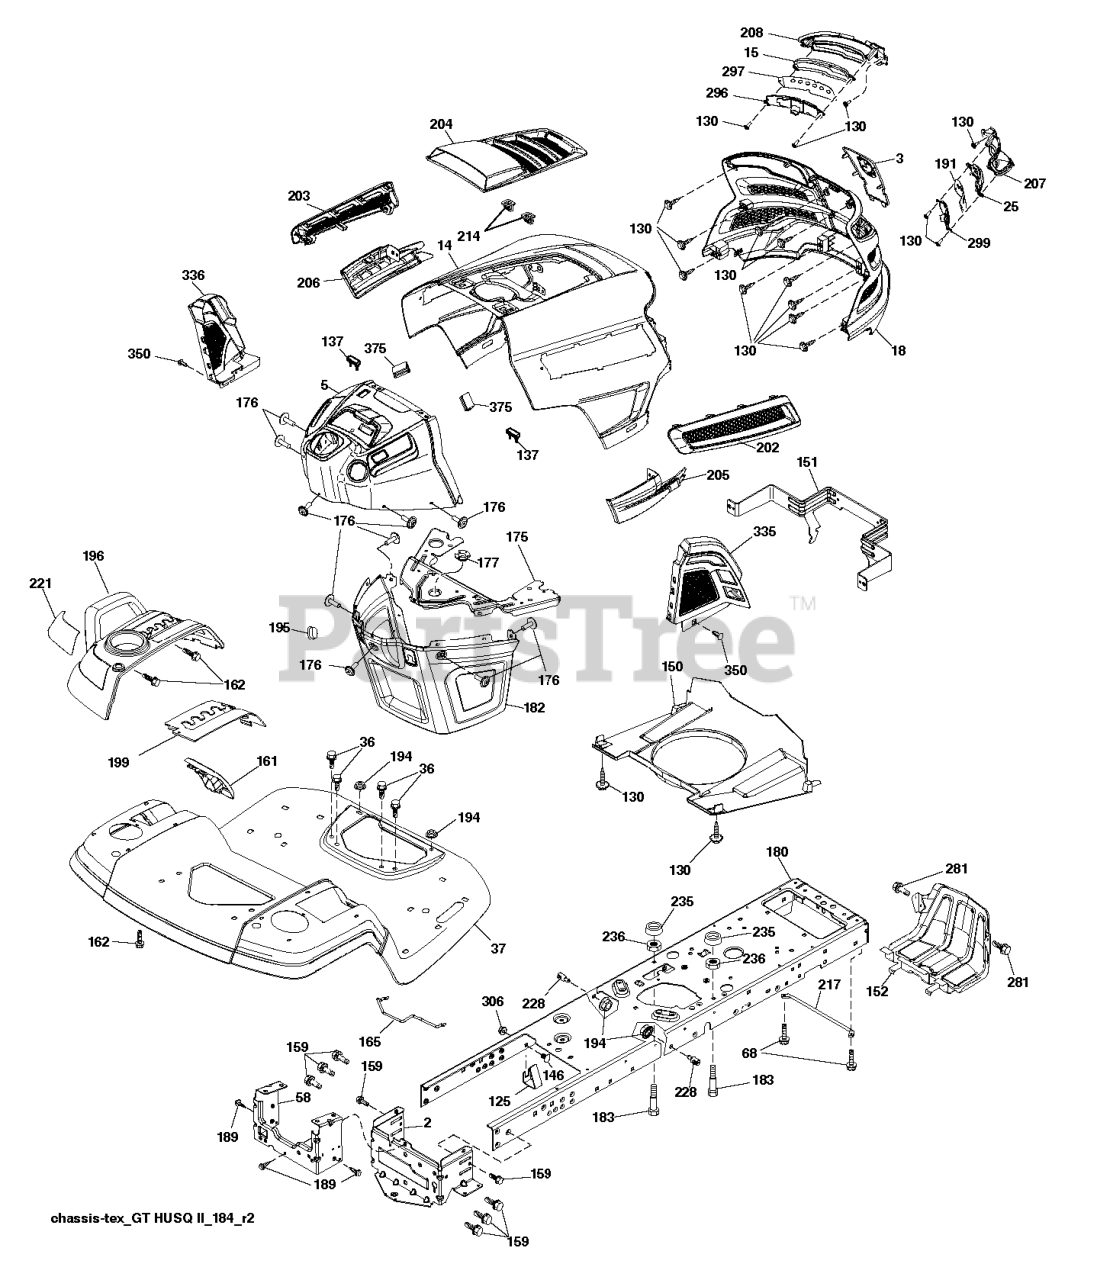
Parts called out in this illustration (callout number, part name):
2	DRAWBAR.LOWER.2PC.18/22
3	APPLIQUE.SUBASM.GT.HUSQ.II
5	DASH.UPR.GT2.DUAL.RD.PT
14	HOOD.ASM.HUSQVARNA.GT.TEX.ORAN
15	LED LIGHT.LH
25	LENS.RH
36	SCREW 5/16"
37	FENDER.PNT.TX.GT.CH/FW/DL.HUSQ
58	DRAWBAR.UPPER.2PC,LRG.FENDER
68	SCR 5/16-18 X 1/2 SELFTAP ZN
125	CLIP.FUEL.LINE
130	SCREW.#10 X 0.750.BOS
137	BUMPER DASH
146	BOLT.RDHD.SHT.SQNK.3/8-16X5/8
150	AIR DUCT.GTV2(1.66"RING HEIGHT
151	BRACKET.PIVOT.HOOD.GT.HUSQ.II
152	SHIELD.BROWNING.PNT.GT.V2
159	SCREW, 3/8-16X3/4
161	CONSOLE.WINDOW.FUEL.HUSQ.GT
162	SCREW.HI-LO.CONSOLE
165	SUPPORT.TANK.REAR.B/TE
175	PLATE.PNT.CROSSMEMBER.HUSQ/PRE
176	SCREW.#10-24X5/8.RN.QU
177	BUSHING STEERING
180	CHASSIS.LT/GT.BOLTED
182	DASH.LOWER.COMMON.12V.ADAPTOR
183	BOLT.5/16-18X1-1/4 FULL THD
189	SCREW
191	INSERT INFLECT.RH
194	NUT LOCK HEX FLANGE 5/16-18
195	PLUG.HOLE.DASH.LOWER.12V.BLK
196	SUBASM.CONSOLE.HUSQ.GT.DECKLFT
199	PLATE.DECK.LIFT.HUSQVARNA.GT
202	VENT.SIDE.RH.GT.HUSQ.II.
203	VENT.SIDE.LH.GT.HUSQ.II.498
204	VENT.TOP.ASM.HUSQ.GT2
205	SIDE.TRIM.RH.GT.HUSQ.II
206	SIDE.TRIM.LH.GT.HUSQ.II.GRAY
207	BEZEL GT2 LED RH W/ LOWER.ATT
208	BEZEL GT2 LED LH W/ LOWER ATT
214	CLIP.RETAINER.TINNER.
217	ROD.PIVOT.HOOD
221	REFLECTOR.LH.TEX GT HU
228	STUD.FASTNER.W/ANTI-ROTATE
235	SPACER FENDER
236	NUT.CENTERLOCK.5/16-
281	SCREW 3/8-16X1
296	LED LIGHT.LH
297	INSERT REFECT LH
299	LED LIGHT.RH
306	NUT LOCK FLG 3/8-16 UNC
335	COVER.LOWER.DASH.RH.BLACK
336	COVER-LH.LOWER.DASH.GT2.BLACK
350	CLIP.X-MAS.TREE
375	BUMPER CLIP-ON. DASH 1"
